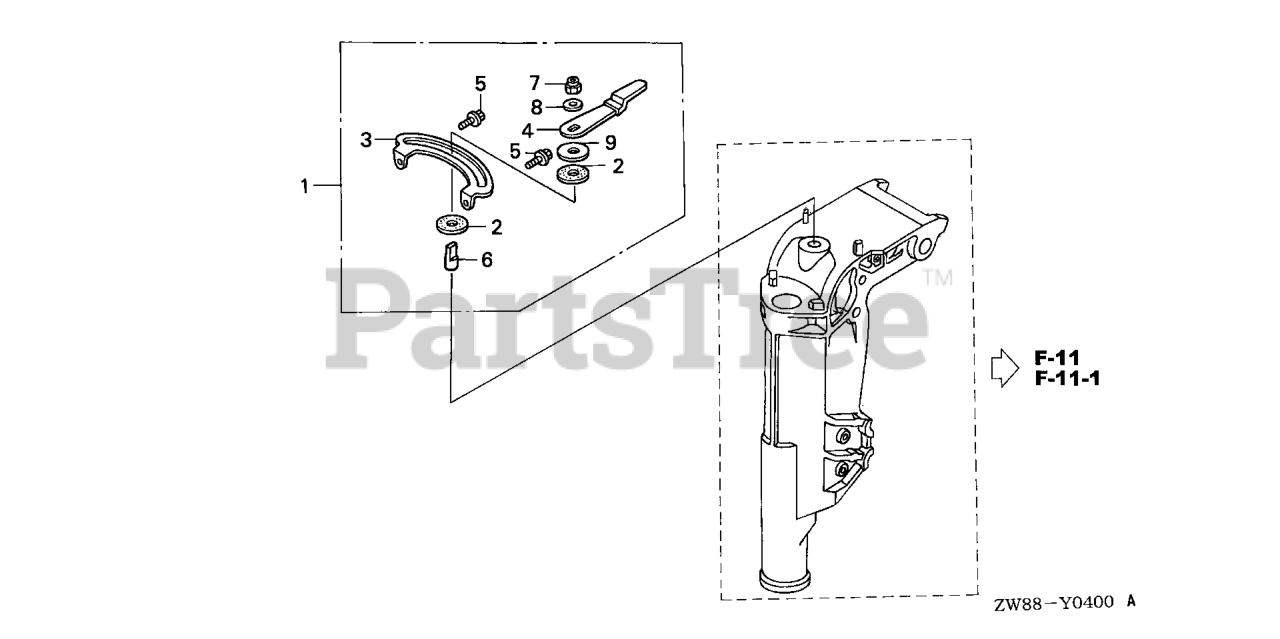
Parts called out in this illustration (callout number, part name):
1	FRICTION KIT, STEERING
1	STEERING KIT, FRICTION
2	BLOCK, FRICTION
3	PLATE, FRICTION
4	LEVER, FRICTION
5	BOLT, FLANGE (6X12)
6	BOLT, STUD (8X26)
7	NUT, SELF-LOCK (8MM)
8	WASHER (8MM)
9	WASHER, NYLON (8MM)
